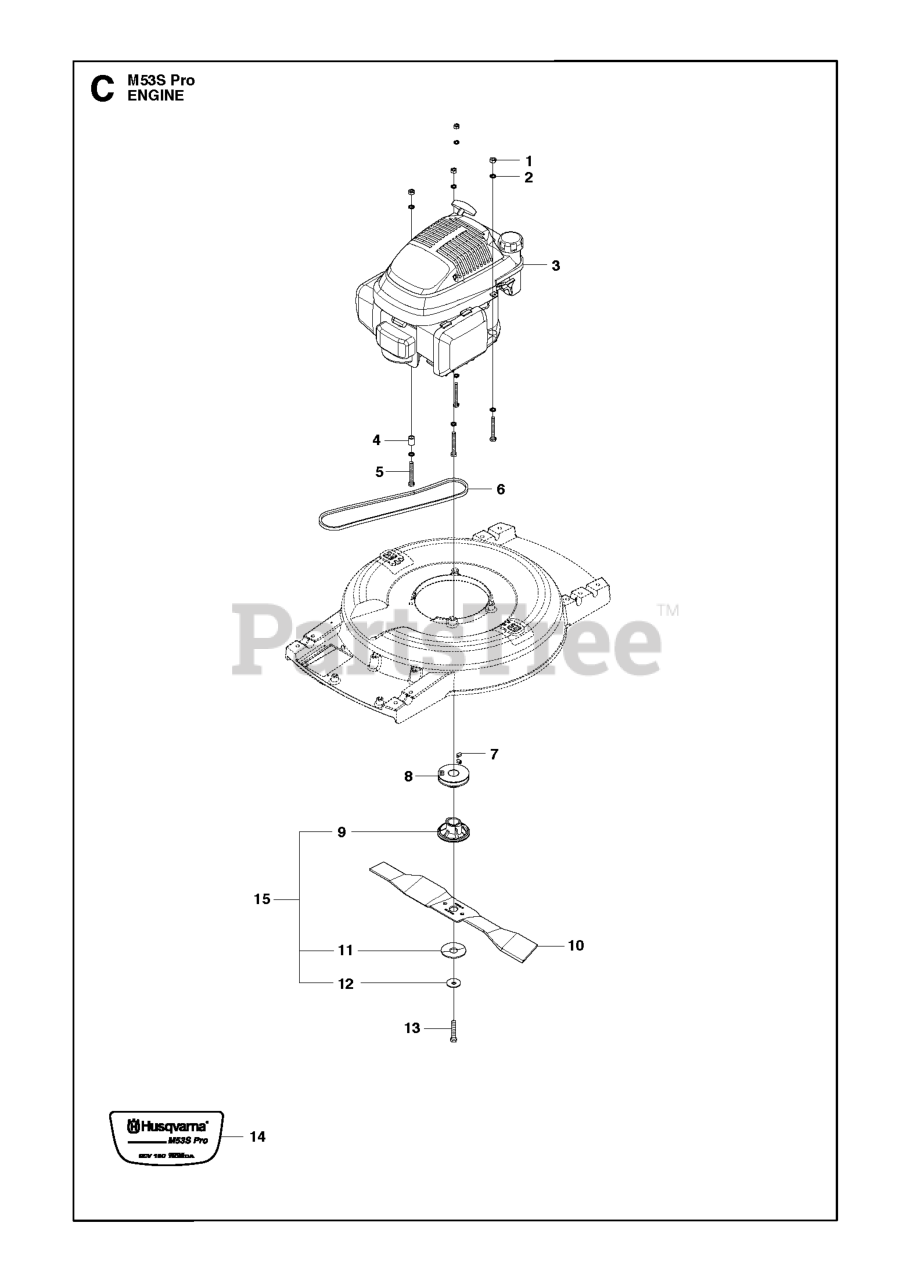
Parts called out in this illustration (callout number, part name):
1	NUT
4	SPACER M53 / M48
6	BELT
8	PULLEY M53S / M48S
9	BLADE SUPPORT
11	SPRING M53 / M48
13	BOLT M53 / M48
